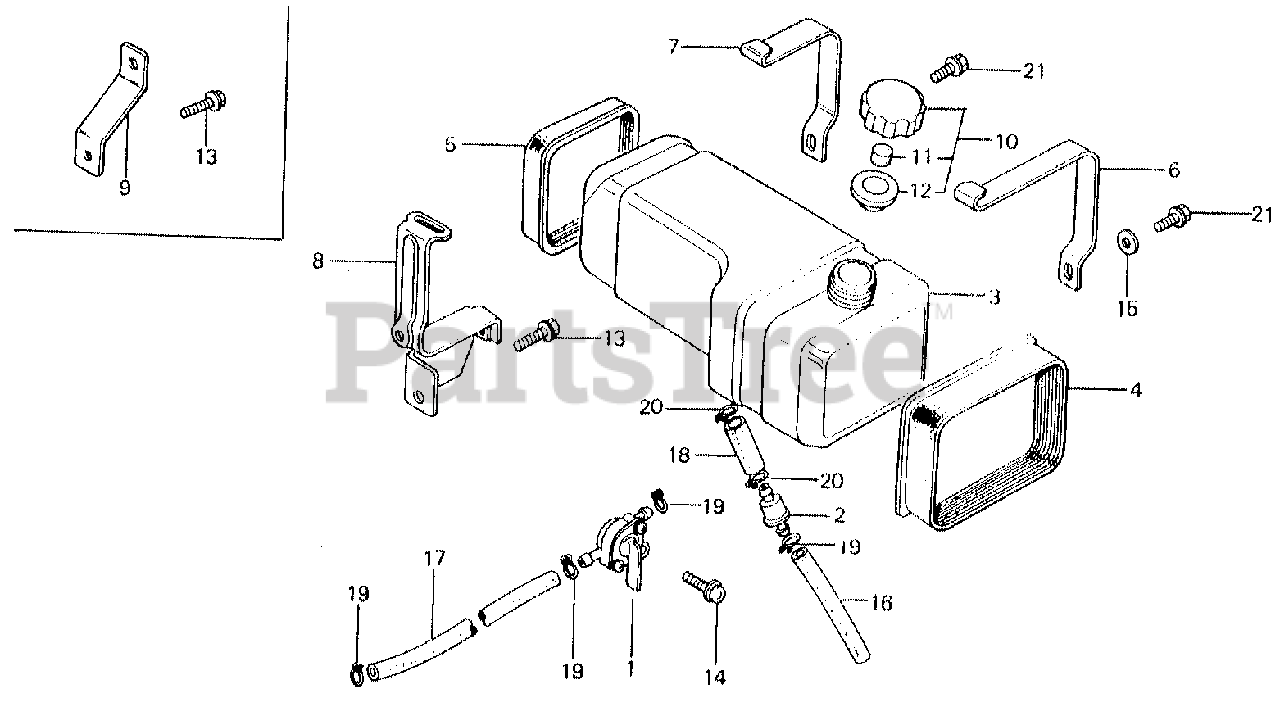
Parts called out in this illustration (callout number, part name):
1	PETCOCK ASSY.
2	FILTER, FUEL
3	TANK, FUEL
4	RUBBER A, FUEL TANK MOUNTING
5	RUBBER B, FUEL TANK MOUNTING
6	BAND A, TANK MOUNTING
7	BAND B, TANK MOUNTING
8	STAY B, TANK
10	CAP, FUEL TANK
11	SPONGE, FUEL CAP BREATHER
12	GASKET, FUEL CAP
13	BOLT, FLANGE (6X12) (CT200)
14	SCREW-WASHER (5X12)
15	WASHER, PLAIN (6MM)
16	BULK HOSE, FUEL (4.5X3000) (4.5X100)
16	BULK HOSE, FUEL (4.5X3000) (4.5X115)
17	BULK HOSE, FUEL (4.5X3000) (4.5X195)
18	TUBE, FUEL
18	BULK HOSE, FUEL (5.5X8000) (5.5X40)
19	CLIP, TUBE (B8)
20	CLIP, TUBE (B10)
21	BOLT, FLANGE (6X12)
